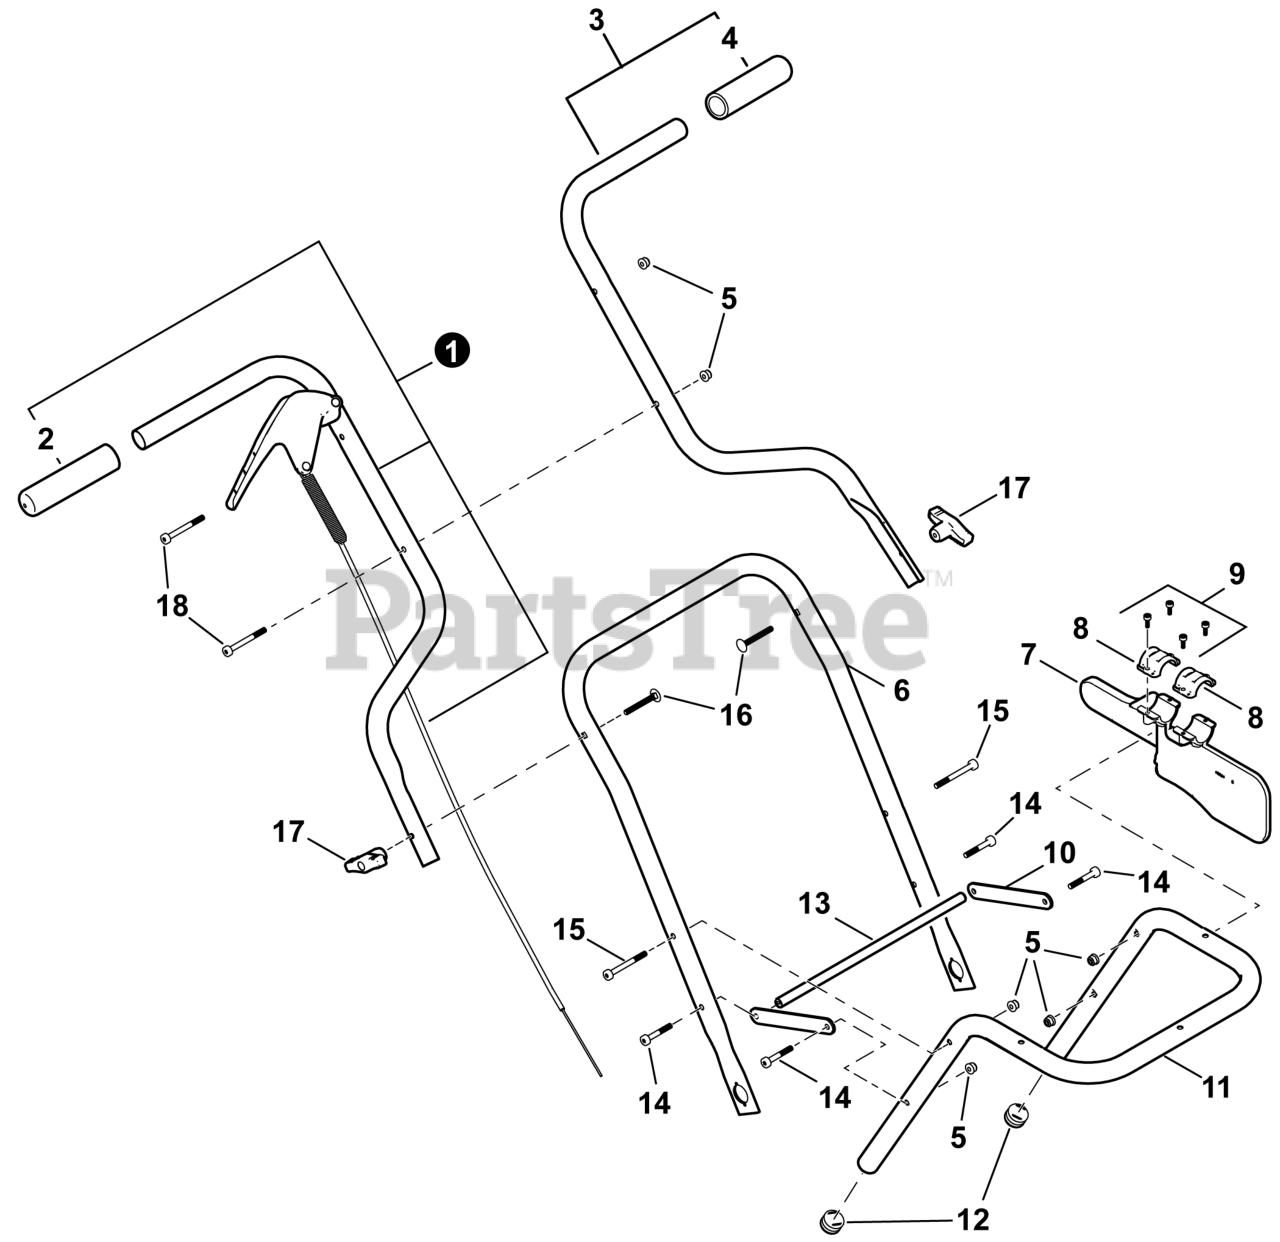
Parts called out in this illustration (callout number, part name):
1	HANDLE CABLE ASSY
2	GRIP, HANDLE
3	HANDLE ASSY
4	GRIP, HANDLE
5	NUT, FLANGE M6
7	DEFLECTOR
8	DEFLECTOR CLAMP
9	BOLT, TORX 4x12
10	BRACE, FRAME
13	BRACE, SPREADER
14	BOLT 6x40
15	BOLT, M6 X 60MM
16	BOLT, M6
17	THUMBSCREW
18	BOLT, M6 X 60MM
